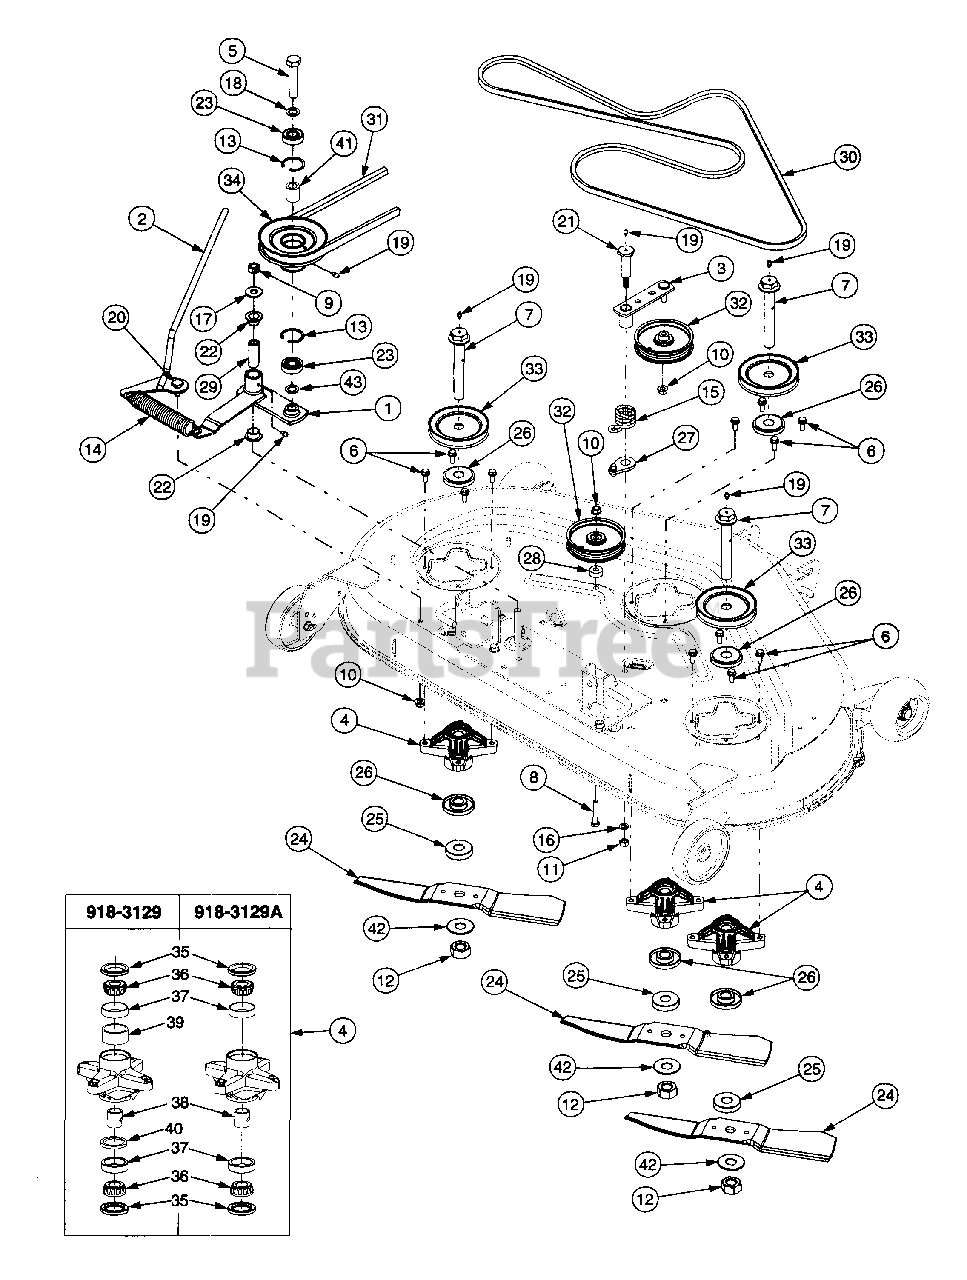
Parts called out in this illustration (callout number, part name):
2	Handle, Tension
3	Idler Arm Assembly
4	Spindle Assembly
5	Screw, Hex Cap, 5/8-18 x 3.0
6	Screw, Hex Wash Ld, 5/16-18 x .75
7	Bolt, Spindle, 3/4-16 x 5.37
8	Screw, Hex Cap, 3/8-16 x 2.0 GR5
9	Nut, Hex Lock, 1/2-20
10	Nut, Flange Lock, 3/8-16
11	Nut, Hex, 7/16-14, GR2
12	Nut, Hex, 3/4-16, GR8
13	Snap Ring, Internal
14	Spring, Ext, .162 Dia x 1.25 OD
15	Torsion Spring, Idler, 1.10 ID x 1.3
16	Washer, Lock, 7/16
17	Washer, Flat, 1/2 x 1.25 x .10
18	Washer, Flat, .63 x 1 x .063
19	Fitting, Lube, 3/16 Drive
20	Bolt, Shoulder, .498 Dia x .340
21	Screw, Shldr, .68 x 2.11, 7/16-14
22	Bearing, Flange, 3/4 ID x .52 LG
23	Bearing, Ball
24	Blade, Mower, 15.94
25	Spacer, Blade
26	Spacer, Deck Spindle
27	Retainer, Spring
28	Spacer, .406 ID x 1.00 OD x .38
29	Spacer, .5 OD x .75 x 2.07 Lg
30	V-Belt, 1/2 x 103.0 Lg
31	V-Belt, B sect x 110.6 Lg
32	Pulley, Flat w/Flanges
33	Pulley, V-Type, 4.0 Dia
34	Pulley, Double
35	Seal, Oil, 1.25 x 1.874 x .25
36	Bearing, Cone
37	Cup, Bearing
38	Spacer, Bring, .780 x .963 x .777
39	Spacer, Bearing, 1.5 x 1.7525 x .8275
40	Spacer, Bearing
41	Spacer, .88 x .635 x 1.25
42	Washer, Flat, .781 x 2.0 x .105
43	Washer, Flat, .65 x 1.25 x .075
